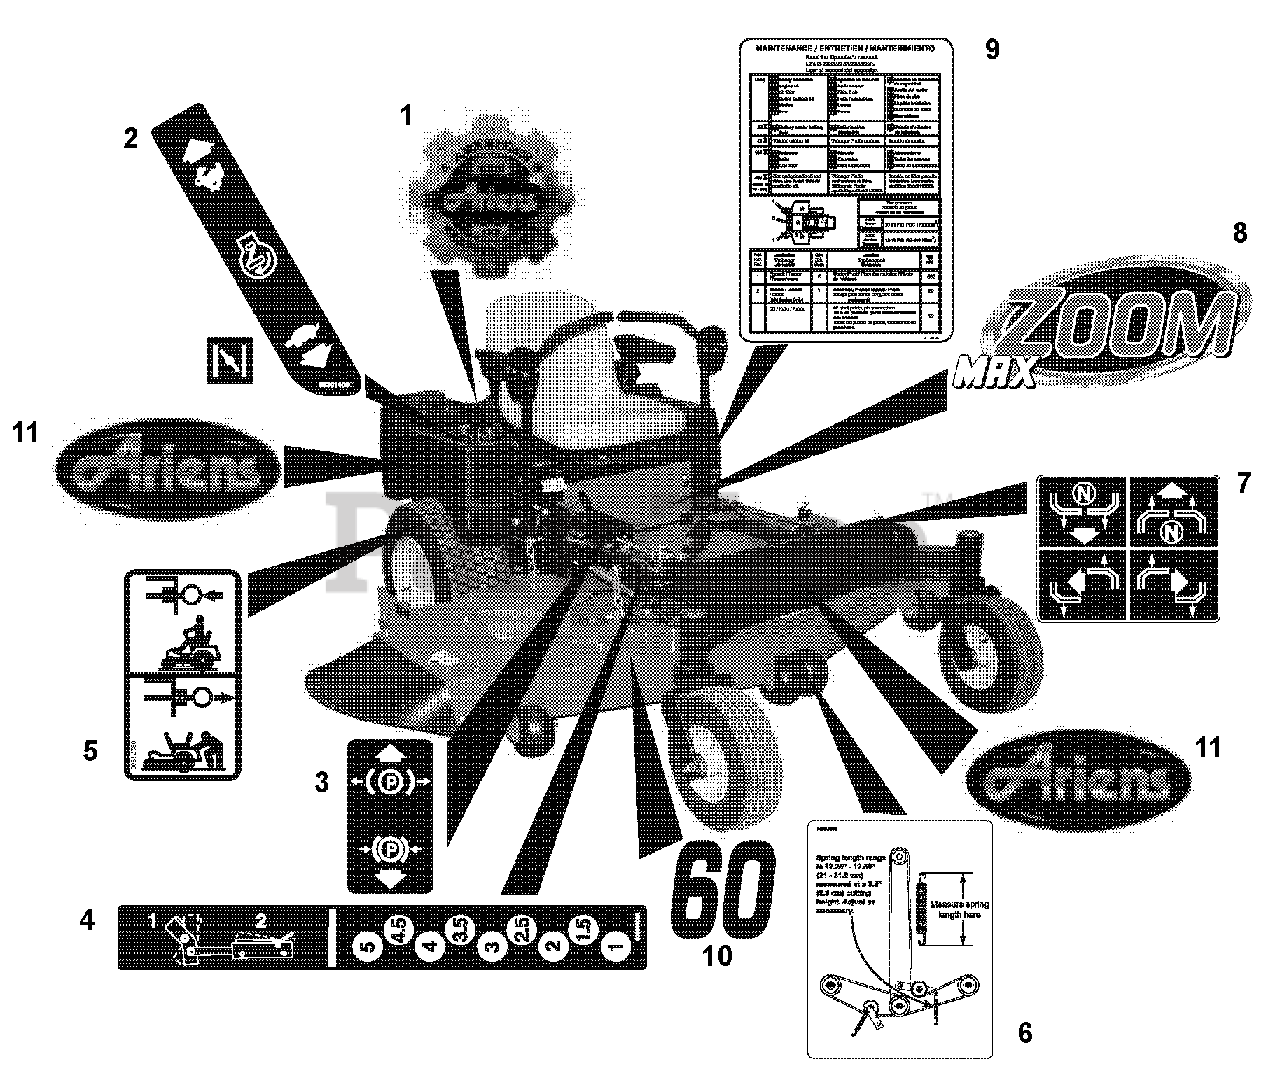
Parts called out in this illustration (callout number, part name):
1	Decal, Ariens Heritage Small
2	DECAL, SPEED CONTROL
3	DECAL, PARKING BRAKE LEVER
4	DECAL, HEIGHT OF CUT COMPACT-Z
5	DECAL, TRANSMISSION DISCONNECT
6	DECAL, BELT ROUTING
7	DECAL, INSTRUCTIONAL-STEERING
8	DECAL, MAX ZOOM
9	DECAL-MAINTENANCE INSTRUCTIONS
10	DECAL, 60"
11	DECAL, ARIENS JEWEL
